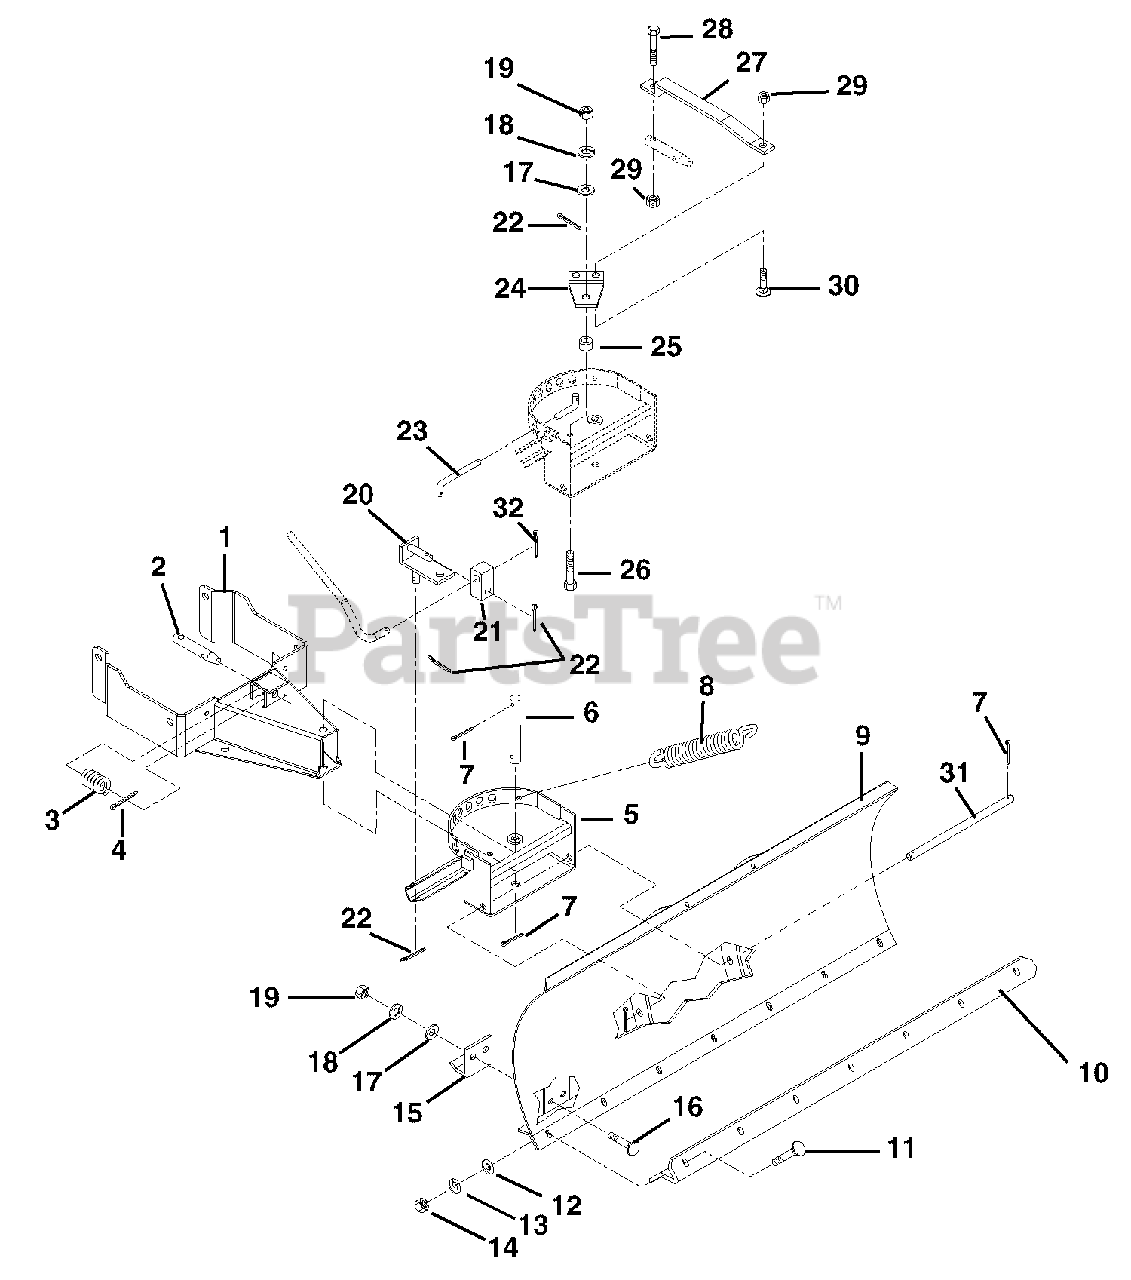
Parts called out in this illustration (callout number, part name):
1	FRAME - PUSH
2	LATCH PIN
3	SG-COMP .080X.85X1.44
4	@PIN-CTR .12X1.00 EXTPRSQCT YZ
5	SUPPORT
7	@PIN-CTR .18X1.00 EXTPRSQCT YZ
8	SG-TENS .187X1.50X9.94 WLD 40
9	BED KNIFE 36 in 5095-36
10	WEAR PLATE
11	@BLT-RDHDSQNK .31-18X1.00 G5YZ
12	@WSHR-FL-STL.38X.875X.083 YWZC
13	@WSHR-LK .31X.078 REG YWZC
14	@NUT-HEX .31-18 YWZC
15	SKID SHOE
16	@BLT-RDHDSQNK .38-16X1.00 G5YZ
17	@WSHR-FL-STL.438X1.00X.083 YWZ
18	@WSHR-LK .38X.094 REG YWZC
19	@NUT-HEX .38-16 YWZC
21	UNIVERSAL BLOCK JOINT
22	@PIN-CTR .12X.75 EXTPRSQCT YWZ
24	PIVOT PLATE
25	SPACER .406X.749X.162
26	@BLT-HEX .38-16X1.00 GR5 YWZC
28	@BLT-HEX .31-18X1.25 GR5 YWZC
29	@NUT-LK-CTR .31-18 YWZC
30	@BLT-RHDSSQNK .31-18X.75 G5YZ
32	PIN-HAIR INT .08X.18X1.18 YWZC
